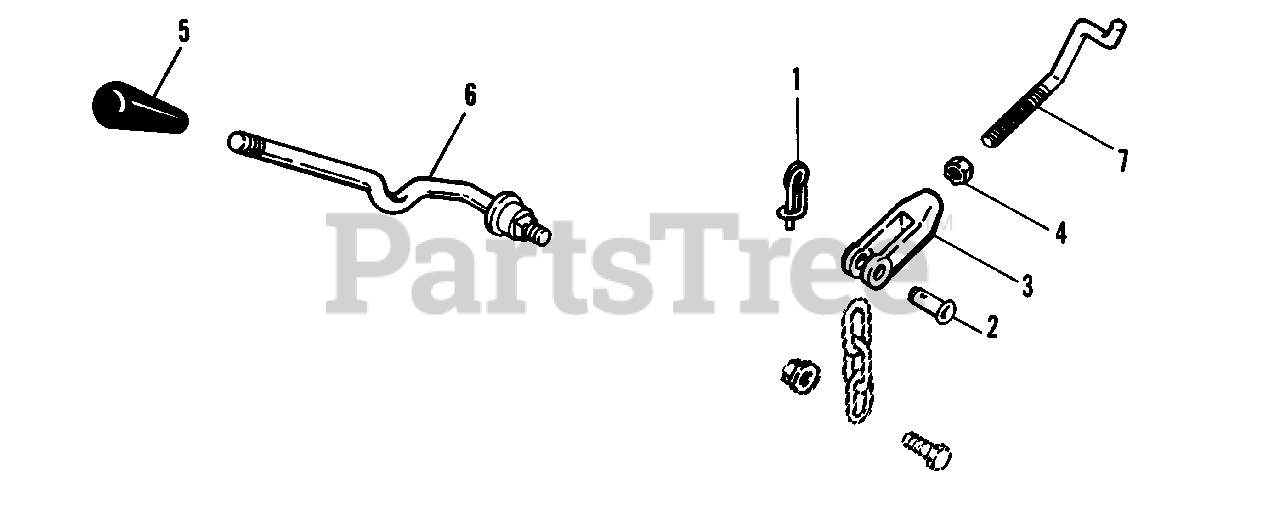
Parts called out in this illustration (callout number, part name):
1	CLIP
2	PIN
4	NUT, 5/16-18
5	KNOB
6	HANDLE, Mower Lift
7	ROD, Lift (Incl. Ref. Nos. 1 thru 4)
